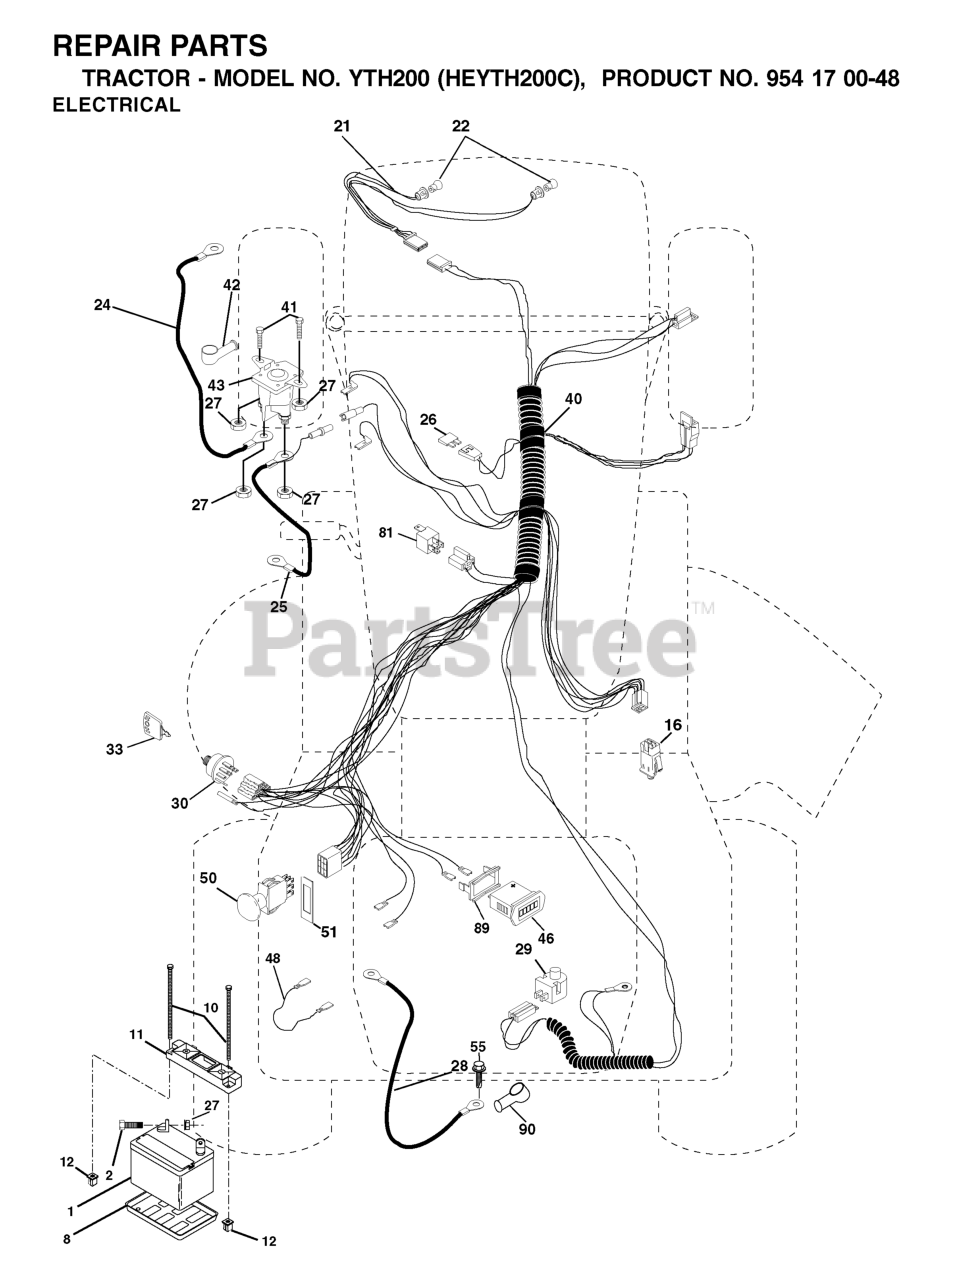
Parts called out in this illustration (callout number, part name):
1	BATTERY 12V .35 AMP
2	BOLT.HEX.1/4.X.3/4.DICHROMATE
8	BATTERY TRAY T
10	BOLT 1/4-20 X 7.5
11	BATTERY HOLDDOWN FRONT MOUNT
12	NUT, PUSH NYLON 1/4" BATTERY
16	SWITCH INTERLOOK PUSH-IN
24	BATTERY CABLE GT
25	CABLE BATTERY 6 GA 22" W/16W
26	FUSE 20AMP
27	NUT
28	CABLE GROUND 6 GA 21" 90T BLK
29	PLUNGER SWITCH (COLOR:OLIVE)
30	IGNITION SWITCH
33	KEY MLD GEN DELTA
40	HARNESS IGN.
41	BOLT
42	TERMINAL COVER
43	SOLENOID
46	HOUR METER
48	ADAPTER.AMMETER
50	RP.PTO.SWITCH.8 TERMINAL.BLACK
51	FRAME RETAINING RING
55	Screw 5/16-18 x 1/2 Hex, Self Tapping 5/16-18 x 1/2
81	RELAY.ASSY.T
89	BRACKET SNAP-IN HOURMETER
